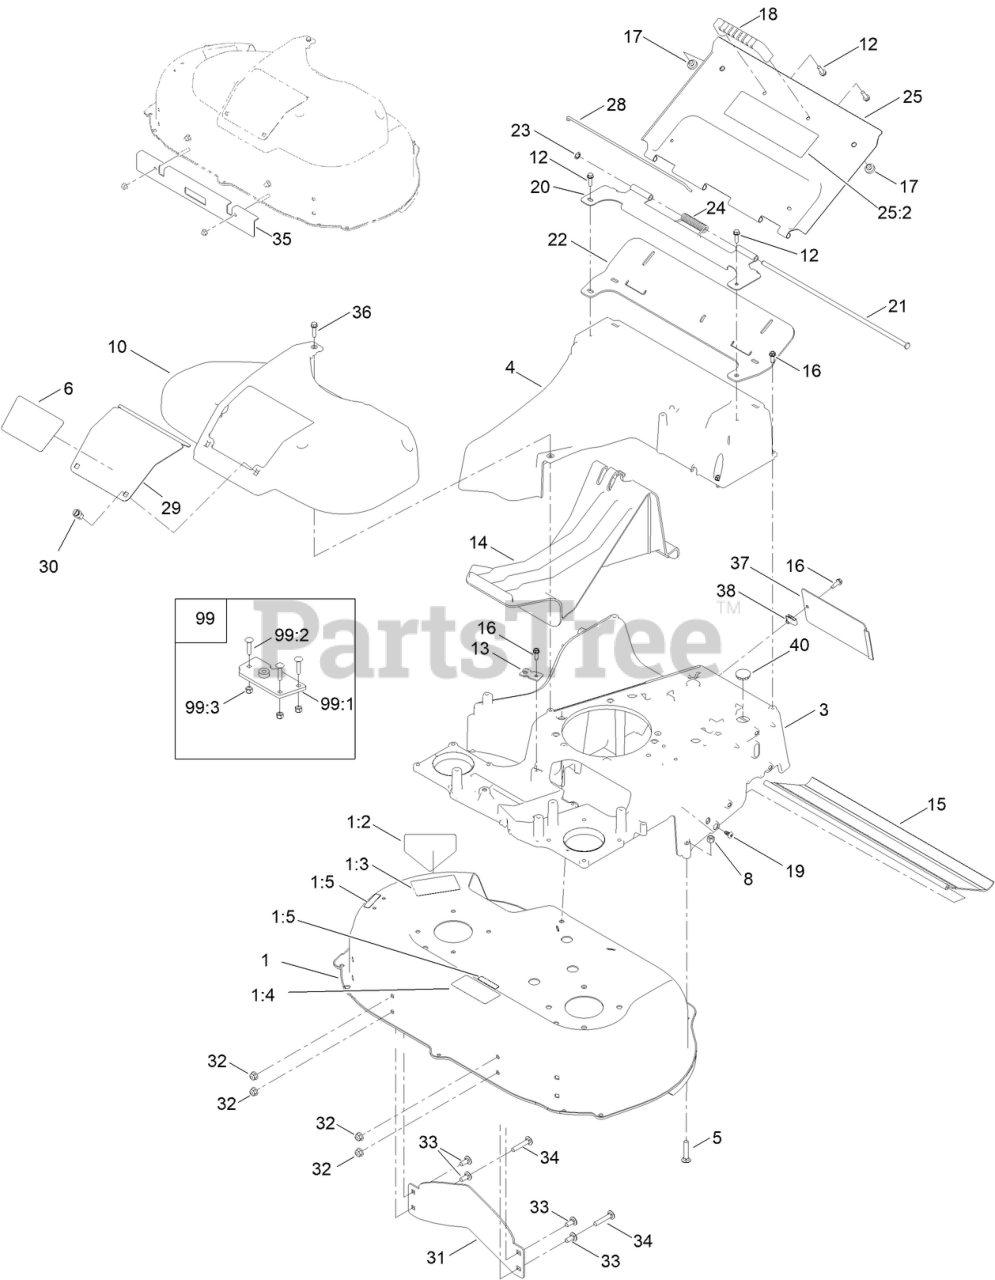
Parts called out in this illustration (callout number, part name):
1	DECK-30 INCH
1:2	DECAL-DANGER
1:3	DECAL-DANGER, CE
1:5	DECAL-WARNING
3	FRAME-30 INCH
5	BOLT-CAR
6	DECAL-76CM
8	NUT-LOCK, NI
10	COVER-BELT
12	SCREW-HWH
13	BRACKET-CABLE, TRACTION
14	PLUG-MULCH
15	SHIELD-TRAILING
16	SCREW-HWHTF
17	BUMPER
18	HANDLE-DOOR
19	SCREW-PTH
20	BRACKET-HINGE
21	PIN-HINGE
22	SEAL-DOOR
23	RING-RETAINING
24	SPRING-TORSION, COVER
25	REAR DOOR ASM
25:2	DECAL-WARNING
28	CLIP-SEAL
29	DOOR-ACCESS
30	FASTENER
31	BAFFLE-CONTROL
32	NUT-HF, NI
33	SCREW-CARR
34	SCREW-CARR
35	PLATE-DECK
36	SCREW-HWHTF
37	COVER-FRAME
40	PLUG-BUTTON
99	FRAME PLATE KIT
99:1	PLATE-FRAME
99:2	SCREW-CARR
99:3	NUT-LOCK, NI
